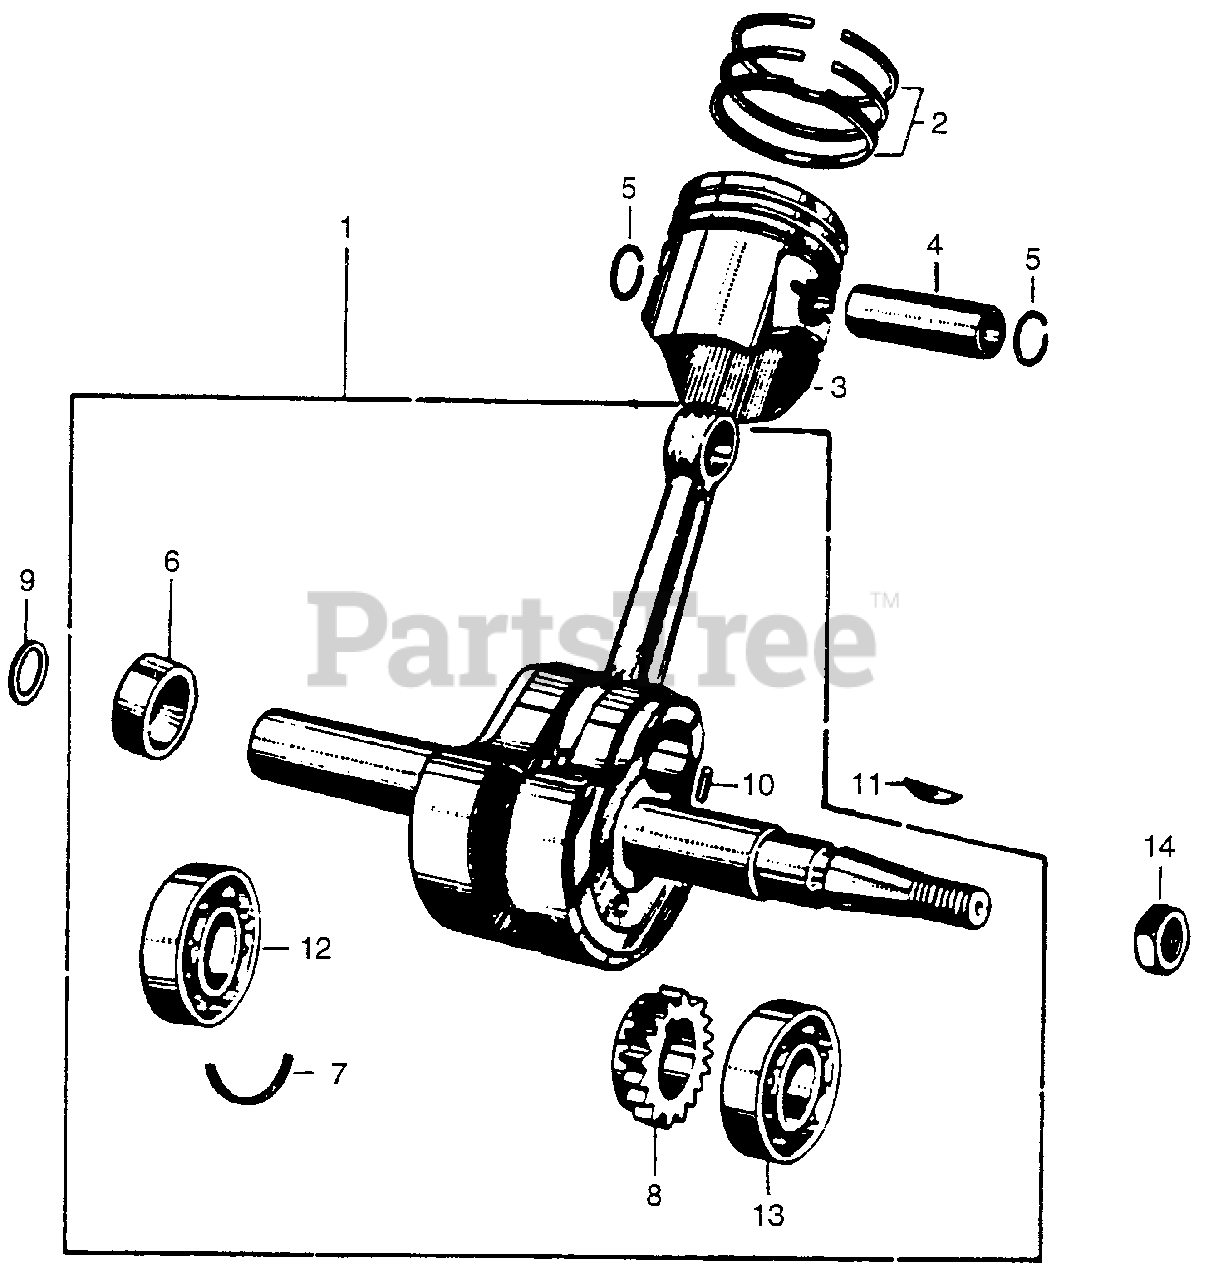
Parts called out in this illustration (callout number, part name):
1	CRANKSHAFT ASSY. (N/A: SEE COMPONENTS)
2	RING SET, PISTON (STD)
2	RING SET, PISTON (OVER SIZE)
3	PISTON (STD)
3	PISTON (OVER SIZE) (0.25)
3	PISTON (OVER SIZE) (0.50)
3	PISTON (OVER SIZE) (0.75)
4	PIN, PISTON (NOT AVAILABLE)
5	CLIP, PISTON PIN (18MM)
6	COLLAR, CRANKSHAFT (NOT AVAILABLE)
7	RING, BALL BEARING SET (NOT AVAILABLE)
8	GEAR, TIMING
9	WASHER, LOCK (8MM)
10	PIN, TIMING SPROCKET KNOCK (NOT AVAILABLE)
11	KEY, WOODRUFF
12	BEARING, BALL (6305SHS)
12	BEARING, RADIAL BALL (6206SHS)
13	BALL BEARING (62055)
14	NUT, HEX. (14MM)
